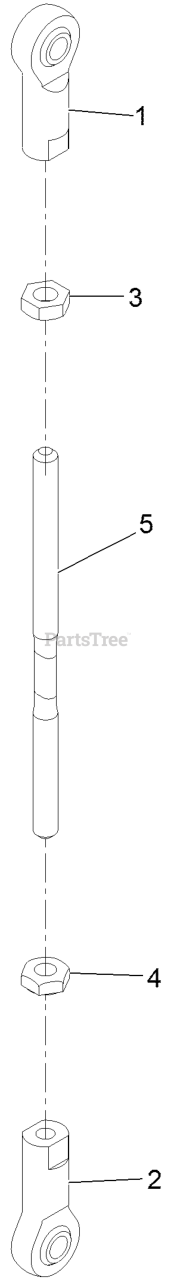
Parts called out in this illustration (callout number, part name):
1	ROD END-BALL JOINT
2	JOINT-BALL, LH
3	NUT-JAM
4	NUT-JAM
